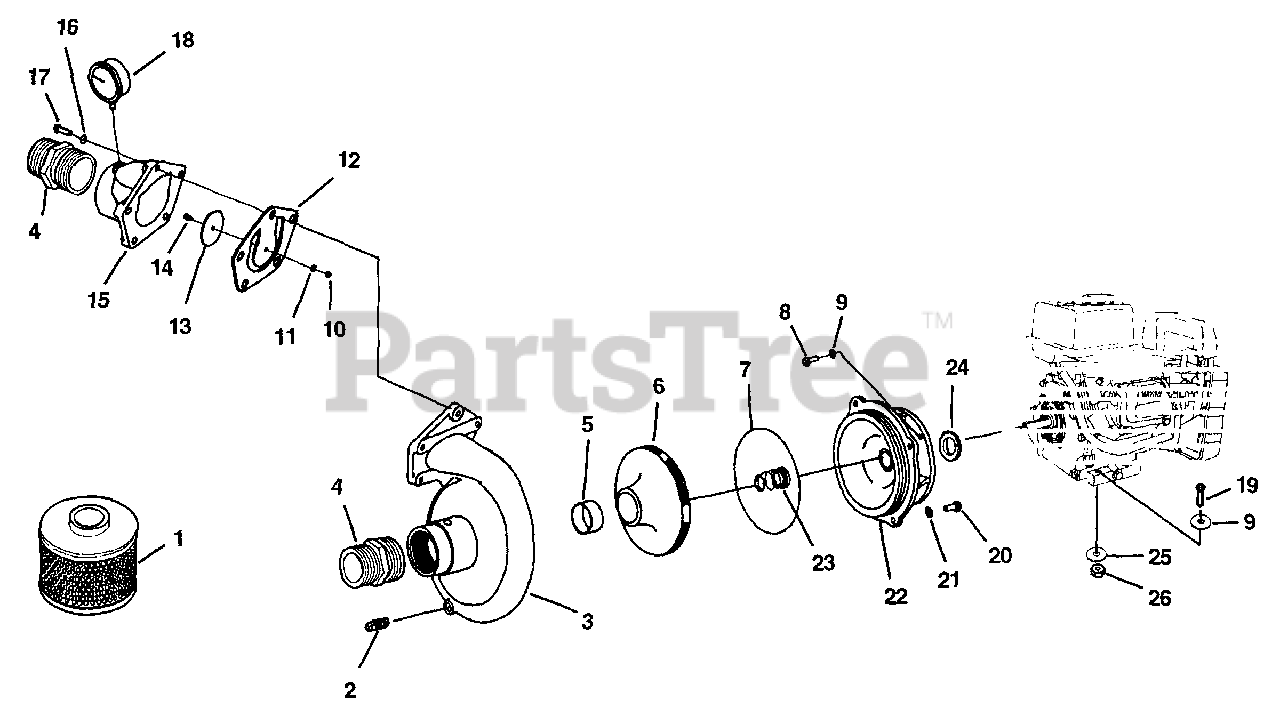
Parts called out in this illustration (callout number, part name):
1	STRAINER 2 1/2-8 NPS
2	PLUG-Drain
3	PUMP BODY
4	NIPPLE 2 1/2-7 1/2 NH x 2 1/2-8 NPT
5	BEARING
6	IMPELLER
7	"O" RING
8	SCREW-Hex Hd. (3/8-16 x 1)
9	WASHER-Flat (3/8)
10	NUT-Hex (12-24)
11	WASHER-Flat (#12)
12	VALVE-Flapper
13	WEIGHT-Valve
14	SCREW-Hex Hd. Mach (12-24 x 5/8)
15	BODY-Valve
16	WASHER-3/8 Collar
17	SCREW-Socket Hd. (3/8-16 x 2)
18	GAUGE-Pressure
19	SCREW-Cap Hex Hd. (3/8-16 x 1 3/4)
20	SCREW-Cap Hex Hd. (1/2-13 x 1)
21	WASHER-Flat (1/2)
22	HOUSING-End
23	SEAL-Shaft
24	SLINGER
25	WASHER-Lock (3/8)
26	NUT-Hex (3/8-16)
